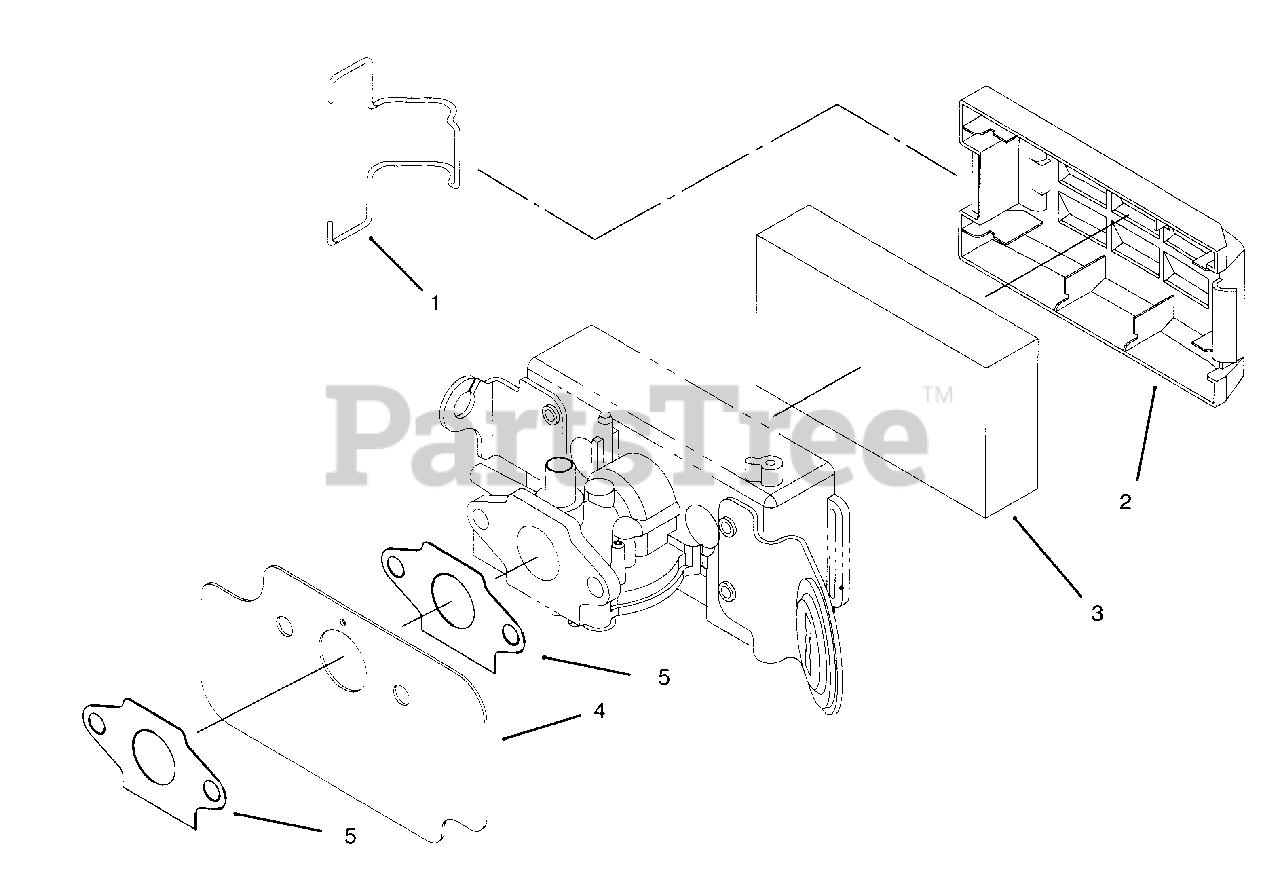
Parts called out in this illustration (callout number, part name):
1	Retainer-Cover
2	Cover-Air Filter
3	Element-Air Filter
4	Shield-Heat
5	Gasket-Carb.
